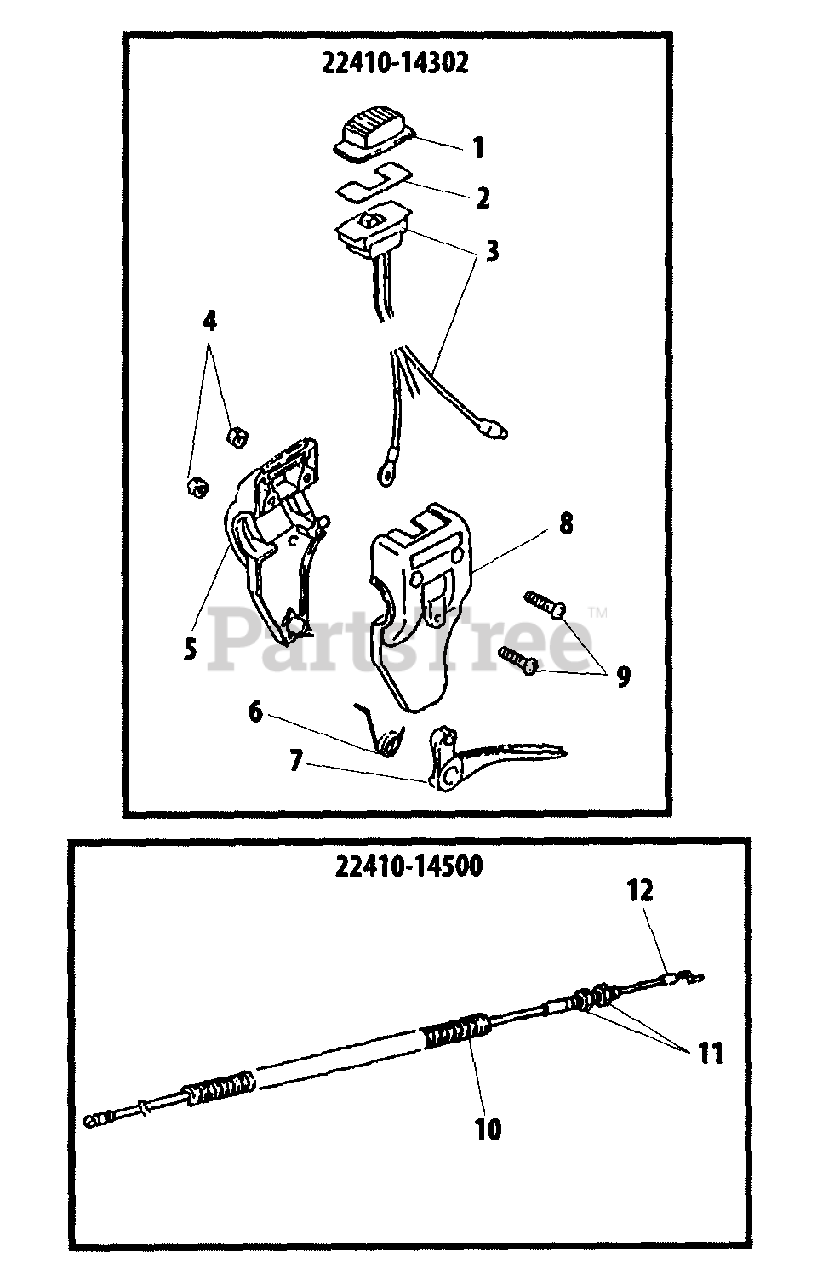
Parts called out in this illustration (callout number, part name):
1	KNOB, SWITCH
2	PLATE, SWITCH
3	SWITCH
4	NUT M5
5	CONTROL HANDLE - RIGHT
6	SPRING, RETURN
7	TRIGGER, THROTTLE
8	CONTROL HANDLE - LEFT
9	SCREW
10	TUBE, PLASTIC PROTECTIVE
11	NUT M6
12	CABLE, THROTTLE
22410-14302	THROTTLE CONTROL KIT
22410-14500	THROTTLE CABLE ASSY
